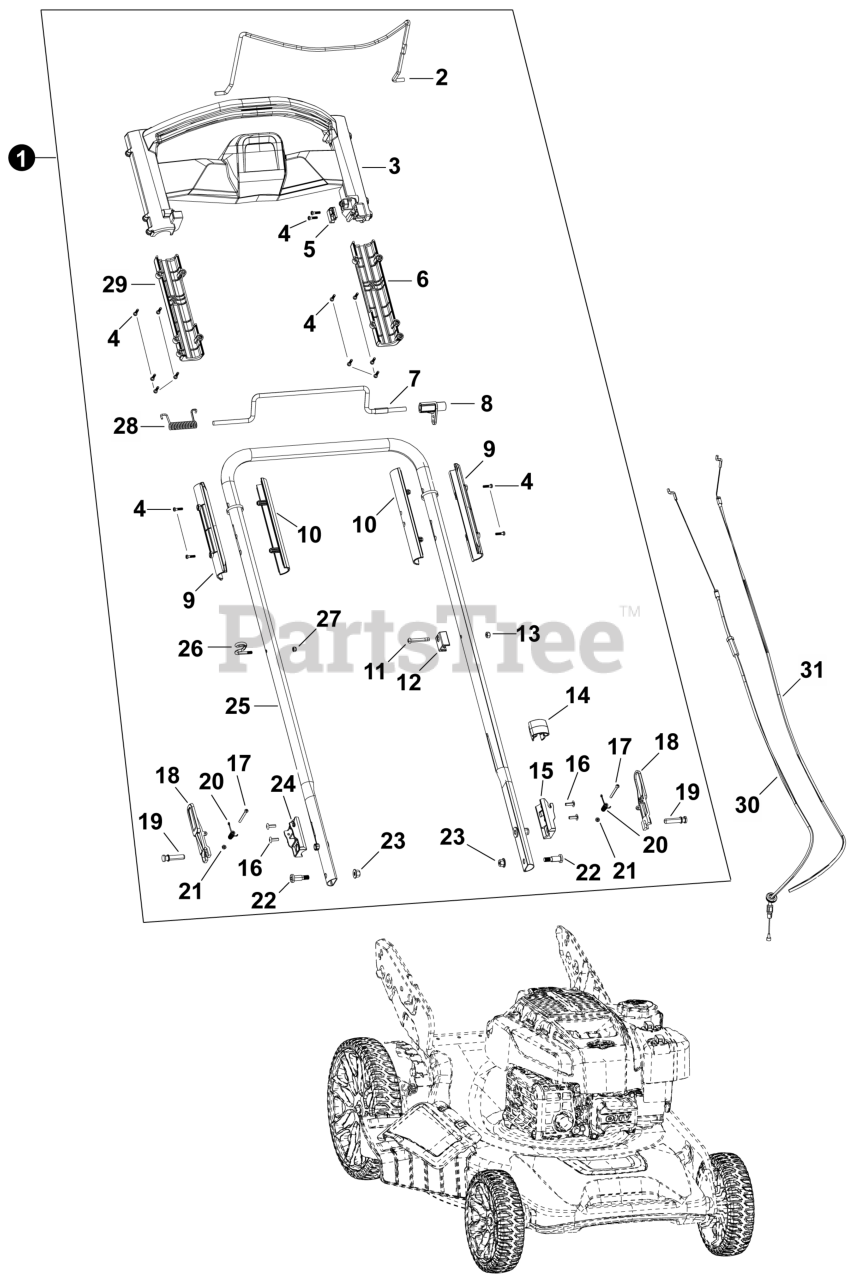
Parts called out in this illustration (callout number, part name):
1	HANDLEBAR ASSY
2	BAIL, OPERATOR PRESENCE
3	HANDLE, OPERATOR
4	SCREW
5	COVER, CABLE
6	COVER, LEFT LOWER HANDLE
7	BAIL, DRIVE
8	BLOCK, ROTATION
9	SLEEVE, LEFT HANDLEBAR
10	SLEEVE, RIGHT HANDLEBAR
11	SCREW
12	BLOCK, CABLE
13	NUT
14	CLAMP, WIRE
15	PLATE, LOWER LEFT HANDLEBAR
16	RIVET
17	SCREW
18	PLATE, HANDLEBAR ADJ.
19	PIN
20	SPRING
21	NUT
22	SCREW
23	NUT
24	PLATE, LOWER RIGHT HANDLEBAR
25	HANDLEBAR
26	GUIDE, WIRE
26	CORD HOOK KIT
27	SPRING, DRIVE BAIL
27	NUT
28	SPRING, DRIVE BAIL
28	COVER, RIGHT LOWER HANDLE
29	CABLE ASSY., DRIVE
29	COVER, RIGHT LOWER HANDLE
30	CABLE ASSY., DRIVE
30	CABLE ASSY., OPERATOR PRESENCE
31	CABLE ASSY., OPERATOR PRESENCE
